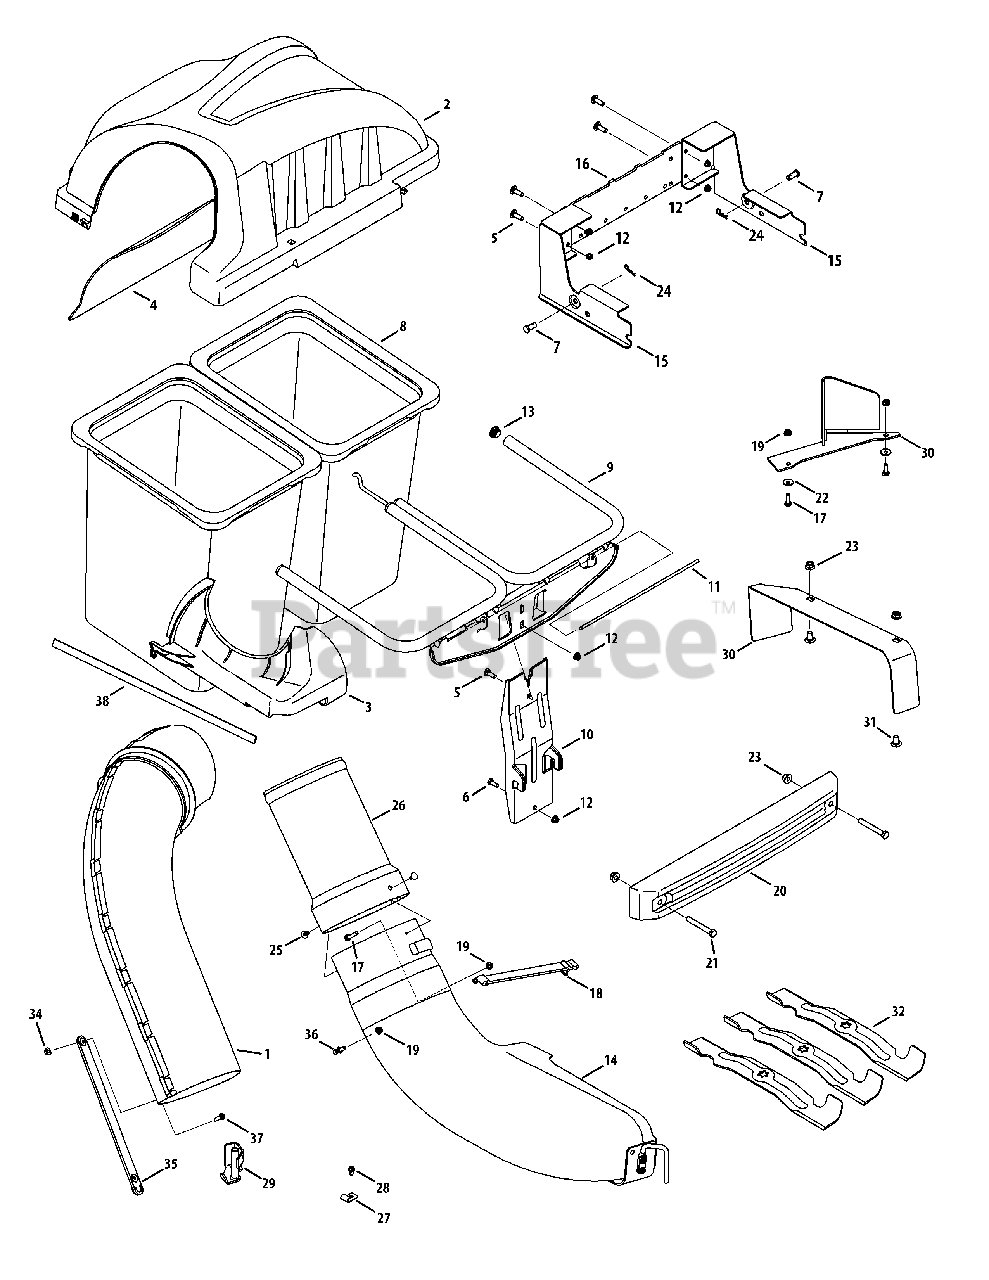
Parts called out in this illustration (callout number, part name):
1	Upper Chute Assembly
2	Twin Bagger Cover Assembly
3	Upper Chute Support
4	Bagger Cover Screen
5	Carriage Screw, 5/16-18 x 1.00"
6	SCREW 5/16-18 x .75 GR5
7	Clevis Pin, .50" Dia.
8	Grass-bag Assembly
9	Twin Bag Support Assembly
10	Vertical Support Bracket
11	Cover Hinge Pin
12	Flange Lock Nut, 5/16-18
14	Discharge Chute Elbow
15	RZT Hitch Bracket Kit
16	Universal Cross Bracket
17	Hex Head Screw, 1/4 - 20 x .75
18	Chute Strap
19	Flange Lock Nut, 1/4 - 20
20	Bagger Weight
21	Hex Head Screw, 3/8 - 16 x 2.75
22	SPRING WASHER BELL
23	Flange Lock Nut, 3/8 - 16
24	Cotter Pin, .080 x 1.5625 Internal
25	Ratchet Clip, .250
26	Bagger Chute Adapter, 8 x 13.5
27	Retainer Hook Bracket
28	Self-Tap Screw, 1/4-20 x .500
29	Chute Stop Bracket
30	Deck Baffle, 50"
31	Carriage Bolt, 3/8-16 x 1.00
32	Bagging Blade, 17.90 Lg. Star
33	Chute Discharge Plate
34	Flange Lock Nut, 1/4-20
35	Chute Strap
36	Grass-catcher Pin
37	Machine Screw, 1/4-20
38	Adhesive Strip
